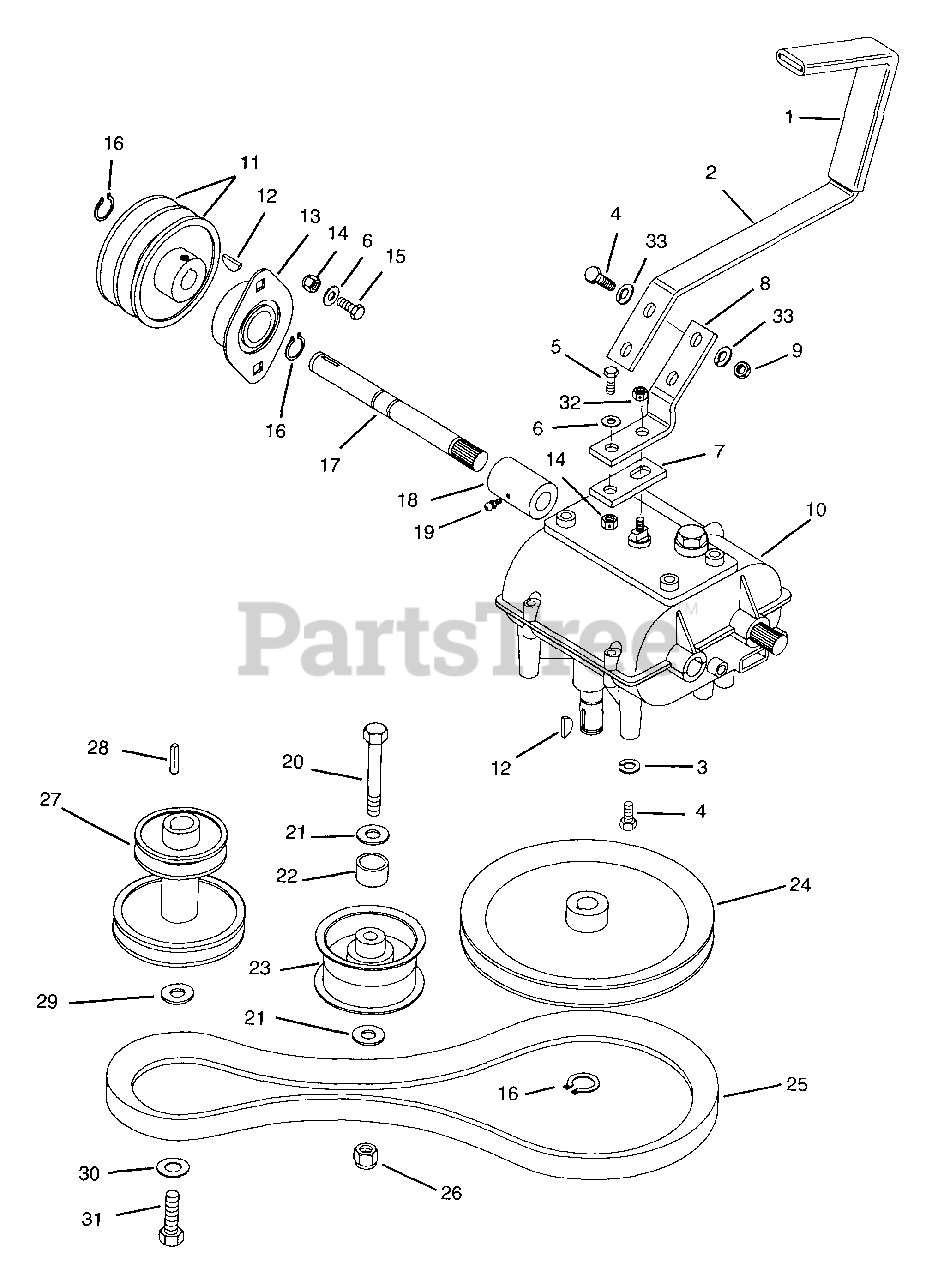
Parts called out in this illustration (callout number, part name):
1	Grip
2	Lever-Transmission Shift
3	Washer-Locking .31 x .078 Regular
4	Bolt-Hex .31-18 x 1.00 Grade 5
5	Bolt-Hex .25-20 x 1.00 Grade 5
6	Washer-Flat-Steel .281 x .62 x .065
7	Plate-Shift
8	Arm-Shift
9	Nut-Locking-Center .31-18
10	Transmission
11	Drive Sheave (Upper) - Pro-100
12	Key-Woodruff .19 x .75
13	Bearing-Flange .625 x 1.875 x .797
14	Nut-Locking-Center .25 -20
15	Bolt-Hex .25-20 x .75 Grade 5
16	Ring-Retaining-External .579 x .93
17	Half Shaft-Transmission, Pro-150
18	Coupler-Transmission Shaft
19	Fitting-Lube .25-28 x .256
20	Bolt-Hex .38-16 x 2.25 Grade 5
21	Washer-Flat-Steel .406 x .812 x .065
22	Spacer .625 x .385 x .55
23	Idler-Pulley Flat 3.25 x .625
24	Pulley-V 7.50 x .63
25	V-Belt A-Section 14.9 x 33/64
26	Nut-Locking-Center .38-16
27	Crank Sheave-Pro1
28	Key-Square .248 X 2.38
29	Washer-Locking .44
30	Washer-Special .42 X 2.000 X 2.50
31	Bolt-Hex M10 X 1.5 X 60
32	Nut-Locking-Center .38-24
33	Washer-Flat-Steel .344 x .688 x .065
